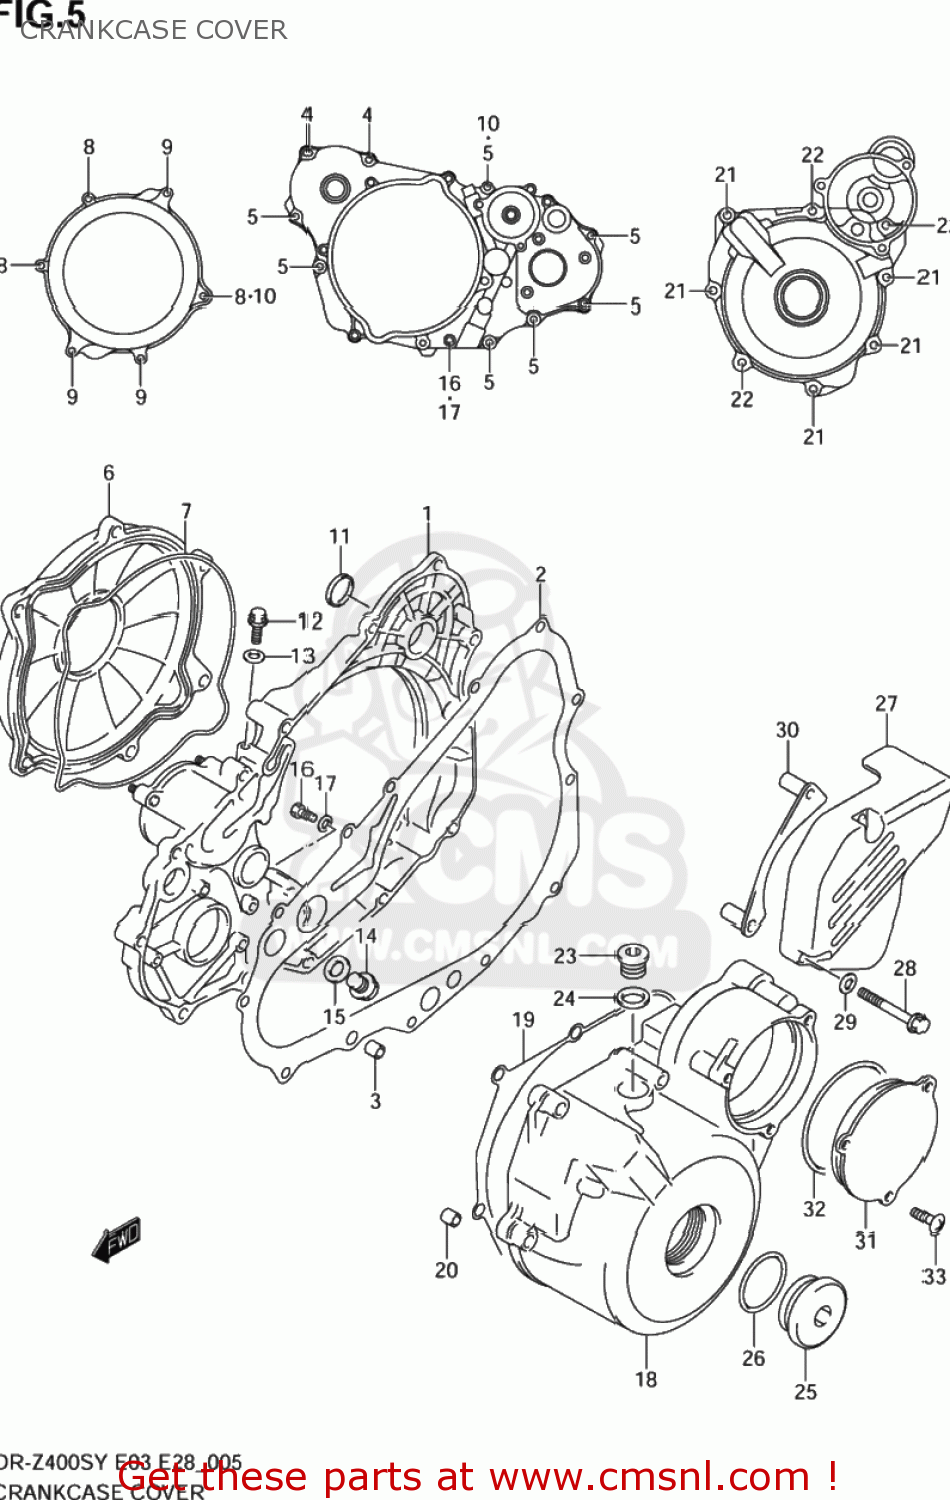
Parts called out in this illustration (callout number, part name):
1	COVER,CLUTCH INNER
2	GASKET,CLUTCH COVER (NAS)
3	PIN
4	SCREW
5	BOLT,G/S SWITC
6	COVER,CLUTCH OUTER
7	O RING,CLUTCH COVER OUTER
8	SCREW
9	BOLT
10	GASKET(5.8X13X1.2) (NAS)
11	PLUG,CLUTCH COVER KICK
12	BOLT
13	GASKET(5.8X13X1.2) (NAS)
14	PLUG(12X10)
15	GASKET(12.1X16.2X3.7) (NAS)
16	BOLT
17	GASKET(6.2X11X1).2 (NAS)
18	COVER,MAGNETO
19	GASKET,MAGNETO COVER (NAS)
20	PIN
21	BOLT,G/S SWITC
22	BOLT
23	PLUG
24	GASKET(13.8X18.8X4.8) (NAS)
25	PLUG
26	O RING(D:3.1,ID:32.7)
27	COVER,ENGINE SPROCKET
28	BOLT
29	WASHER(6.5X14X2)
30	PLATE,FR CHAIN GUIDE
31	COVER,STARTER IDLE GEAR
32	O-RING
33	SCREW
